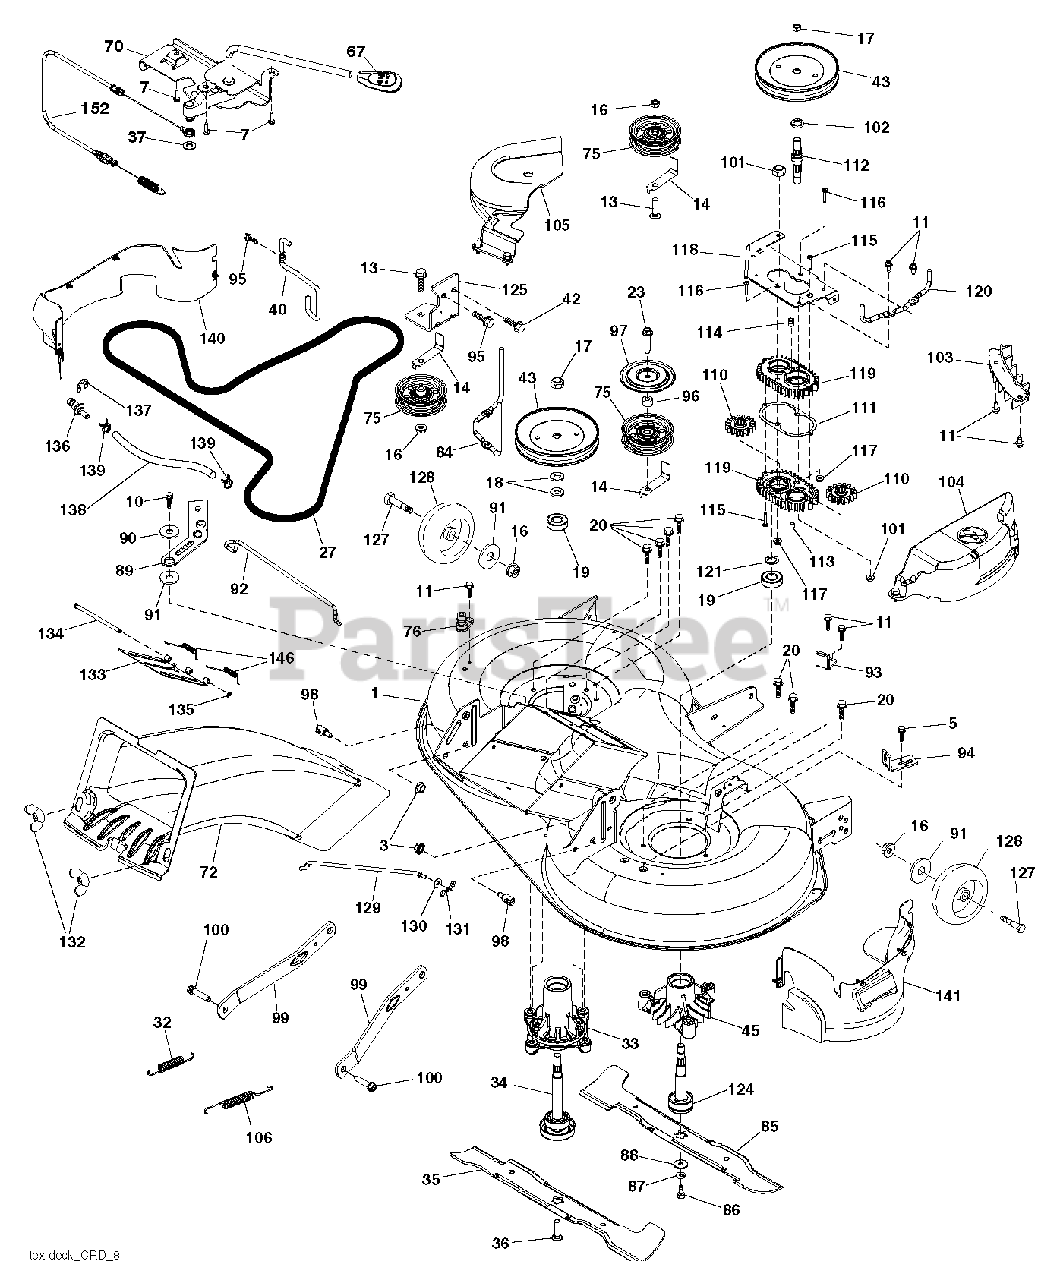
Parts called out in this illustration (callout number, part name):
1	DECK SVCX 97HP.EZ.MLCH.498
3	NUT LOCK HEX FLANGE 5/16-18
5	BOLT.5/16HEX.WHS.HD
7	SCREW.#10 X 0.750.BOS
10	SCREW 3/8-16X1
11	SCREW.1/4-20X5/8
13	BOLT.3/8-16X1.50
14	KEEPER, BELT IDLER
16	NUT LOCK FLG 3/8-16 UNC
17	NUT.FLANGE.LOCK.TOP
18	WASHER.SPACER.MANDREL
20	SCREW, WASHER HEAD
23	SCREW LT
27	BELT V-BELT DRIVE
32	SPRING RETURN
33	HOUSING.MANDREL.4PT.
34	SHAFT.ASM.MDRL.N/GREASE.38
35	BLADE.3N1.LH.CRD.97
36	BOLT.WASHER.ASM.7/16-2
37	WASHER
40	KEEPER BELT ENGINE LH
42	SCREW
43	PULLEY.MANDREL.5.438.PD
45	HOUSING.MANDREL.44/46" VENT
67	HANDLE.CLUTCH.CABLE.LT.TEX.667
70	CLUTCH.ASM.MANUAL.YT.PREDATORQ
75	FLAT IDLER PULLEY
76	1/2" BARB.DECK.WASHOUT.PORT
84	KEEPER.BELT.MANDREL.PULLEY
85	BLADE.3N1.RH.CRD.97
86	BOLT.3/8-24X1.25GR8. LHTHRD
87	LOCKWASHER
88	WASHER.BLADE
89	ARM.BRAKE.97.LH
90	SPACER.RETAINER
91	WASHER
92	ROD ROD BRAKE
93	ARM.BRAKE.97.RH
94	BRKT.CLUTCH.CABLE
95	SCREW, 3/8-16X3/4
96	SPACER
97	PROTECTOR
98	STUD.FASTNER.W/ANTI-ROTATE
99	ARM.SUSPENSION.MOWER.R
100	BOLT.SHOULDER
101	NUT.CROWNLOCK.9/16 -18.UNC
102	SPACER BEARING
103	GUARD GUARD FRONT VENT
106	SPRING.BRAKE.RETURN.38"
110	GEAR GEAR OUTPUT
111	GASKET GASKET GEARCASE
113	PLUG PLUG OIL
114	VALVE VALVE RELIEF
115	SCREW
116	BOLT.CARIGE.SS.1/4-20X1.75GR5
117	NUT T
118	ARM ARM CLUTCHING
119	GEARCASE GEARCASE SUBASM
120	BRACKET KEEPER BELT RH
121	WASHER WASHER
124	MANDREL SHAFT NON/GREASE
125	BRACKET
127	BOLT.SHOULDER.3/8-16X3-5/8.
128	WHEEL. GUAGE RALLY
129	ROD.ANTI.SWAY.48/54"K4
130	WASHER
131	PIN.COTTER.5/16.BOW TI
132	KNOB.HANDLE.3/8.TRI-POINT.BLAC
133	DOOR
134	PIN PIN.HINGE
135	E-RING.5/16"
136	PLUG WASHOUT PORT HOOKUP
138	HOSE.3/8ID.BULK.12"
139	HOSE.3/8.CLAMP (2 2)
